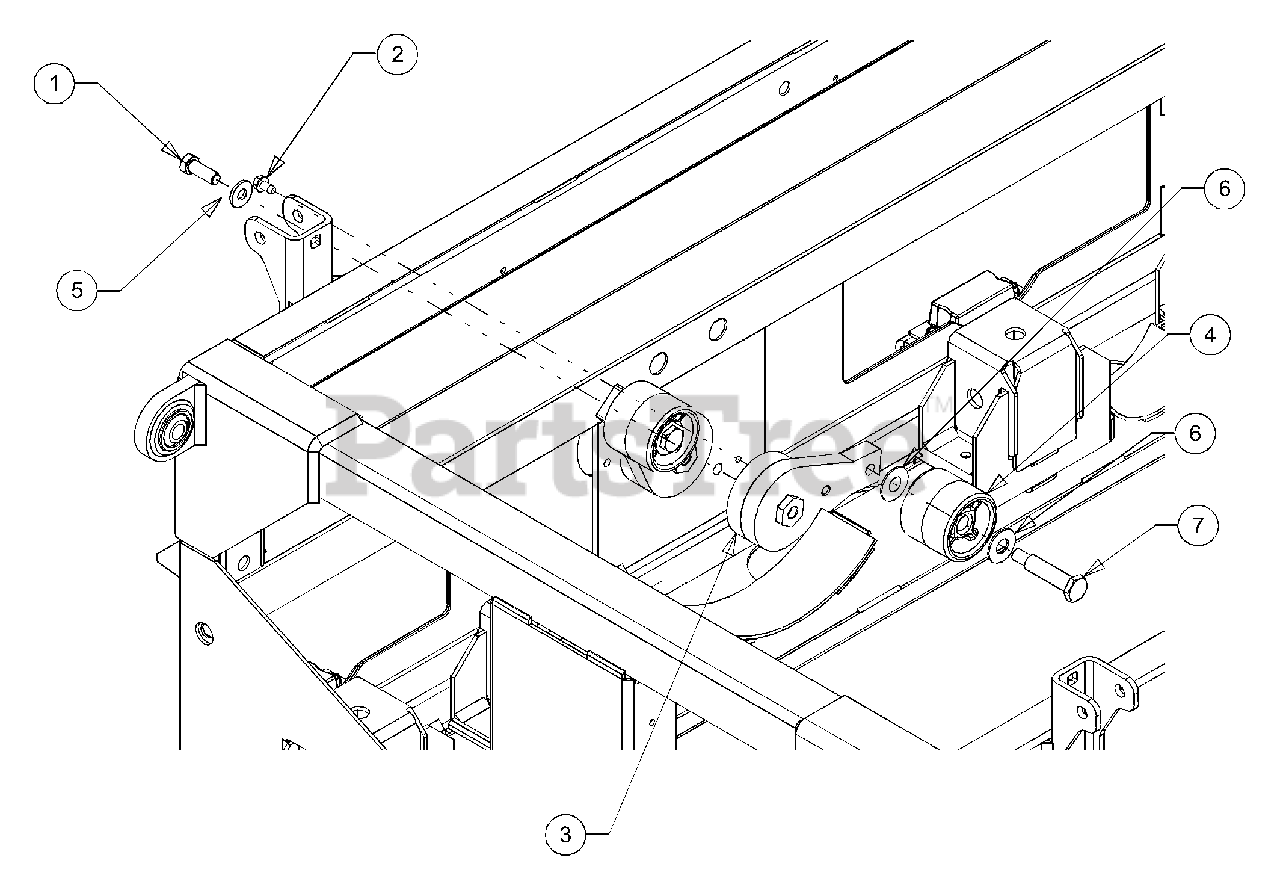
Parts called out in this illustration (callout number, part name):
1	Shoulder Screw, .50 x 1.825
2	Washer, Flat, .510 x 1.12 x .060
3	Washer, Flat, .385 x .870 x .092
4	Roller, Chain
5	Adjuster, Rotary
6	Screw, Self-tapping, 1/4-20 x .5
7	Hex Screw, 3/8-16 x 1.0
